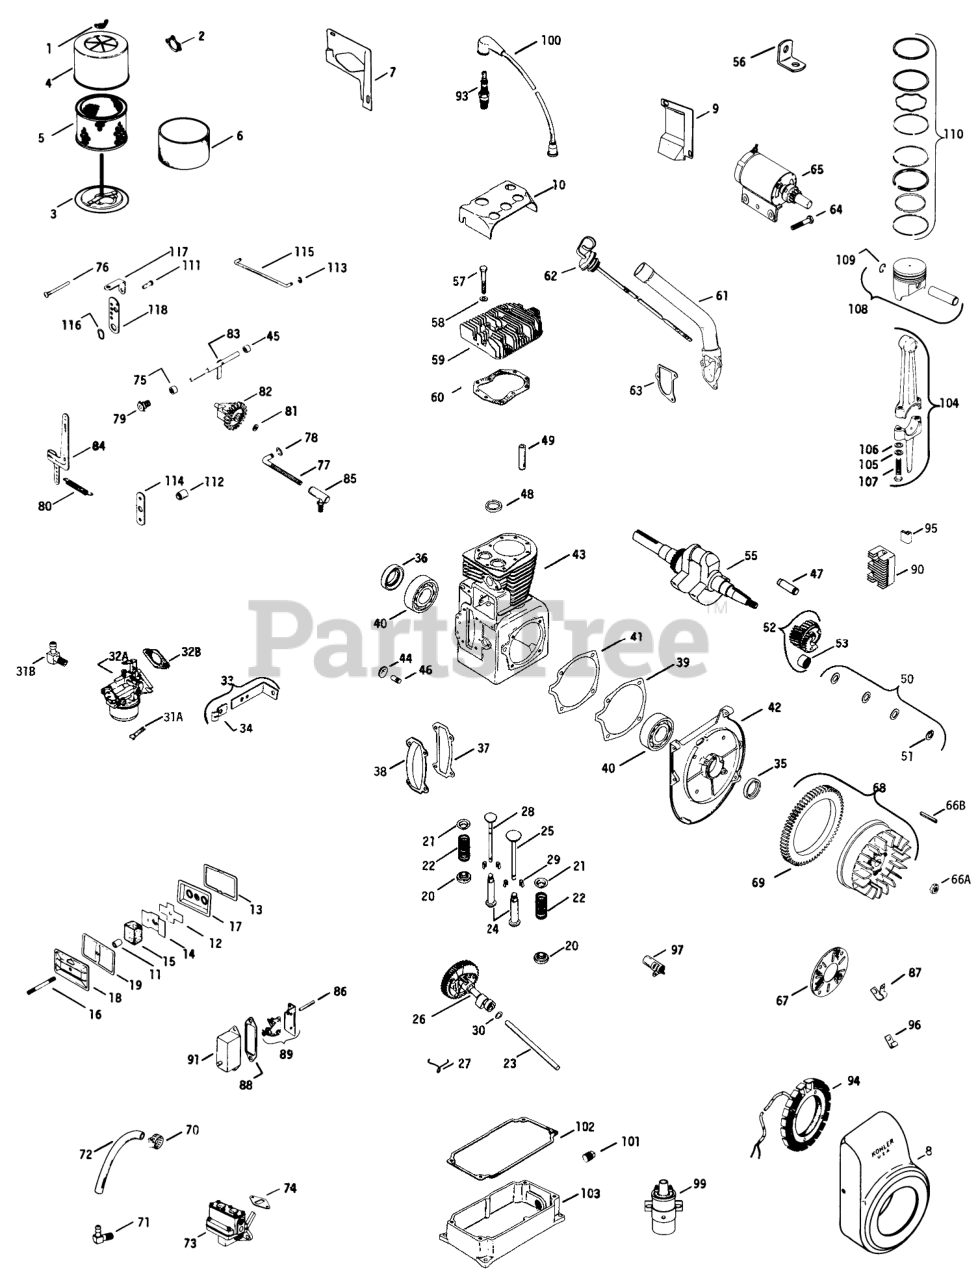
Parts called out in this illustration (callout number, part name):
1	Nut-Wing
2	Gasket-Air Horn
3	Base, air cleaner
4	Cover-Air Cleaner
5	Element
6	Precleaner
7	BaffLe side air
8	Housing-Blower
9	Baffle, cylinder
10	Baffle, head
11	Seal
12	Reed
13	Gasket
14	Baffle breather
15	Filter Breather
16	Stud, valve cover
17	Plate
18	Cover valve
19	Gasket
20	Rotator
21	Retainer-Spring
22	Spring
23	Pin (Service)
24	Tappet
25	Valve-Intake
26	Camshaft-assembly
27	Spring-Actuating
28	Valve exhaust
29	Keeper, Valve
30	Spacer
31A	Screw sitd. hd.
31B	Elbow
32A	Carburetor-assembly
32A	Repairkit
32B	Gasket
33	Bracket, choke
34	Clip
35	Seal, Front OiI
36	Seal rear oil
37	Gasket
38	Cover
39	Gasket
40	Ball Bearing
41	Gasket
42	Plate Bearing
43	Block, cylinder-assembly (Use 45_782_02 Miniblock)
44	Plug
45	Bearing
46	Shaft-Govemor
47	Shaft
48	Insert
49	Guide Valve
50	Kit-Spacer
51	Retainer
52	Gear
53	Bearing,needle
55	Crankshaft
56	Lift Cable
57	Screw
57	Screw-H.C.
58	Washer
59	Head, cylinder
60	Gasket, head
61	Tube, fill
62	Dipstick
63	Gasket
64	Screw
65	Starter-assembly
65	Kit, Brush & Spring
65	Washer
66A	Nut
66B	Key
67	Screen grass
68	Flywheel-assembly
69	Gear Ring
70	Clamp
71	Elbow
72	Line Fuel
73	Pump, fuel
74	Gasket, pump
75	Spacer
76	Pin-GovemorStop
77	Rod ball joint
78	Retainer Rod
79	Bushing
80	Spring-Governor
81	Washer
82	Gear, Governor
83	Shaft, Governor
84	Lever, Governor
85	Ball Joint
86	Rod, breaker
87	Clip
88	Gasket, Cover
89	Breaker
90	Regulator
91	Cover breaker
93	Plug, spark
94	Stator
95	Connector
96	Clip
97	Condenser
99	Coil
100	Kit, Hi-Tension
101	Plug
102	Gasket
103	Base, oil pan
104	Rod, conn.-assembly (Std.)
104	Rod, conn.-assem. (.010 U.S.)
105	Washer
106	Washer
107	Screw, connecting rod
108	Piston-assembly (Std.)(Include pin & retainers)
108	Piston-assembly (.003)(Includes pin & retainers)
108	Piston-assembly (.010)(Includes pin & retainers)
108	Piston-assembly (.020)(Includes pin & retainers)
108	Piston-assembly (.030)(Includes pin & retainers)
109	Pin, Retainer
110	Ring set-Std. & .003
110	Ring set-.010
110	Ring set-.020
110	Ring set-.030
111	Clamp, swivel wire
112	Spacer
113	Retainer Rod
114	Bellcrank
115	Rod, throttle
116	Washer
117	Spacer
118	Bracket
118	Gasket Set
118	Mini block
118	Short Block
118	Service Engine
